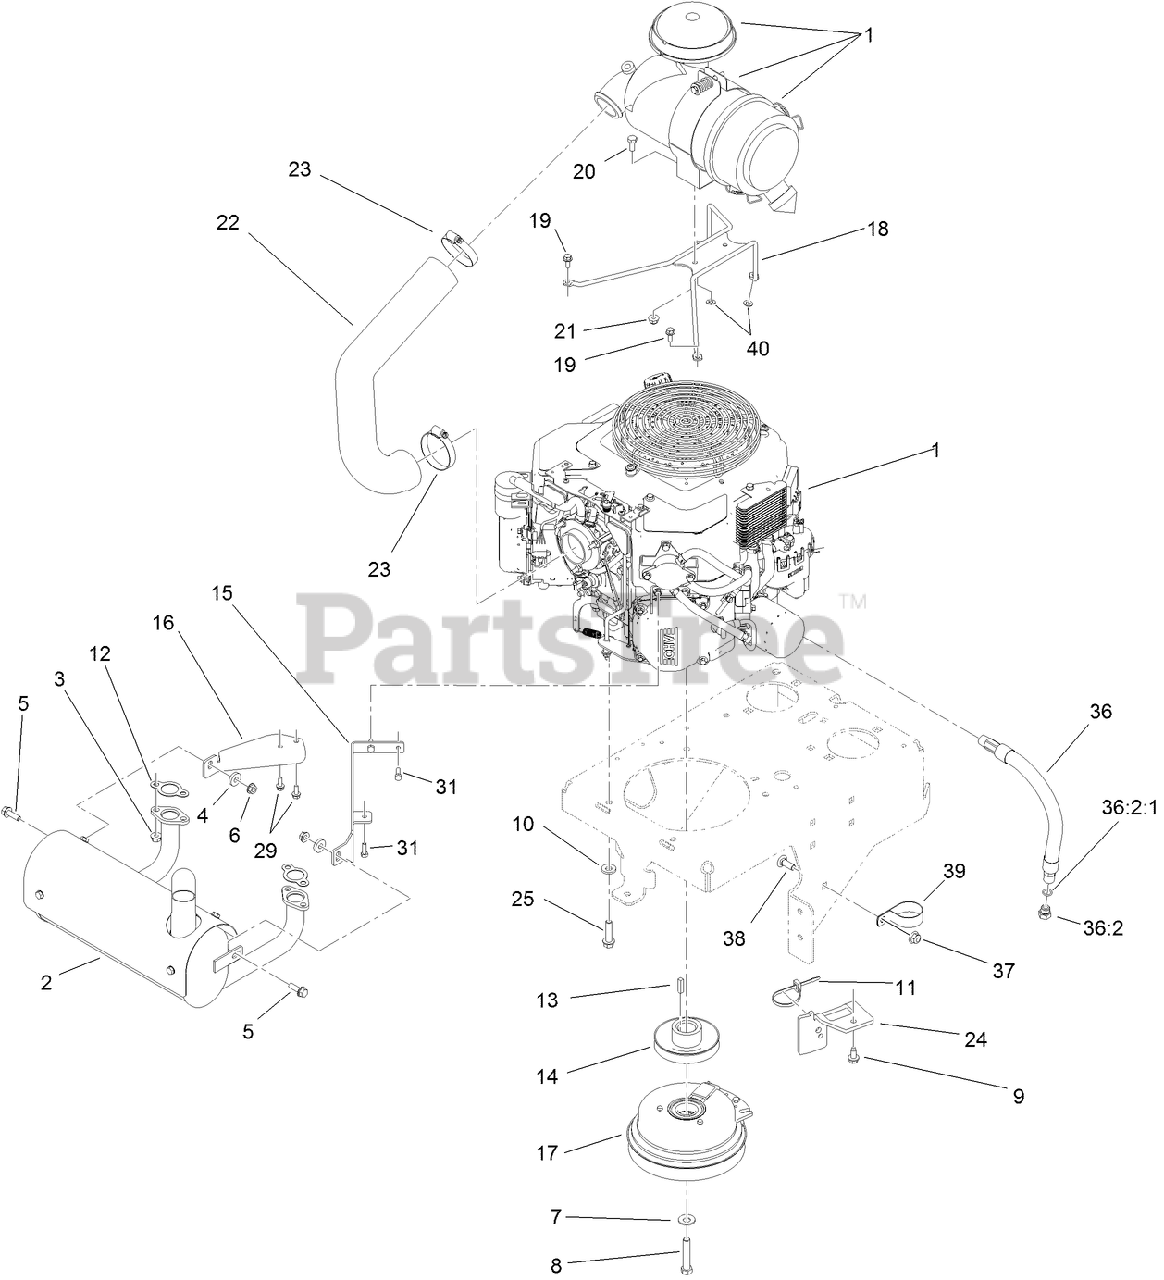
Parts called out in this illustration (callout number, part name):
2	MUFFLER
3	NUT-FLANGE
4	SPACER
5	SCREW-HHF
6	NUT-HF
7	WASHER-SPRING
8	SCREW-HH
9	SCREW-HWHTF
10	WASHER-BELLEVILLE
11	TIE-CABLE
12	GASKET-EXHAUST
14	PULLEY
15	BRACKET-MUFFLER, LH
16	BRACKET-MUFFLER, RH
17	CLUTCH
18	MOUNT-CLEANER, AIR
19	SCREW-HHF
20	SCREW-HH
21	NUT-HF, NI
22	HOSE-INTAKE, AIR
23	CLAMP-HOSE
24	BRACKET-ANCHOR, CLUTCH
25	SCREW-HWH
29	SCREW-HWHTF
31	SCREW-HH
36	OIL DRAIN HOSE ASM
36:2	PLUG-HH
36:2:1	O-RING
37	NUT-HF, NI
38	SCREW-CARR
39	CLAMP-R
40	WASHER-PLAIN
